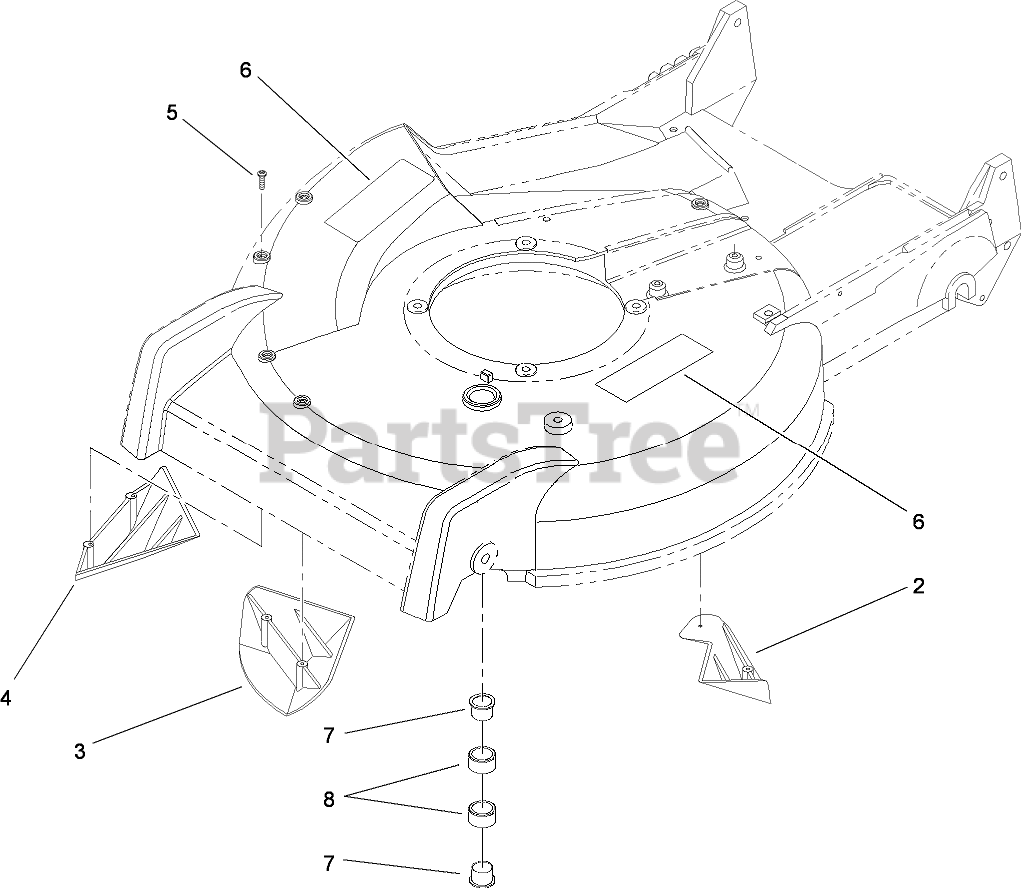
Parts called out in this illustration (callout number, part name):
2	KICKER-REAR
3	KICKER-FRONT
4	KICKER-RH
5	SCREW-PPH
6	DECAL-DANGER
7	CAPLUG (L-9)
8	BEARING
